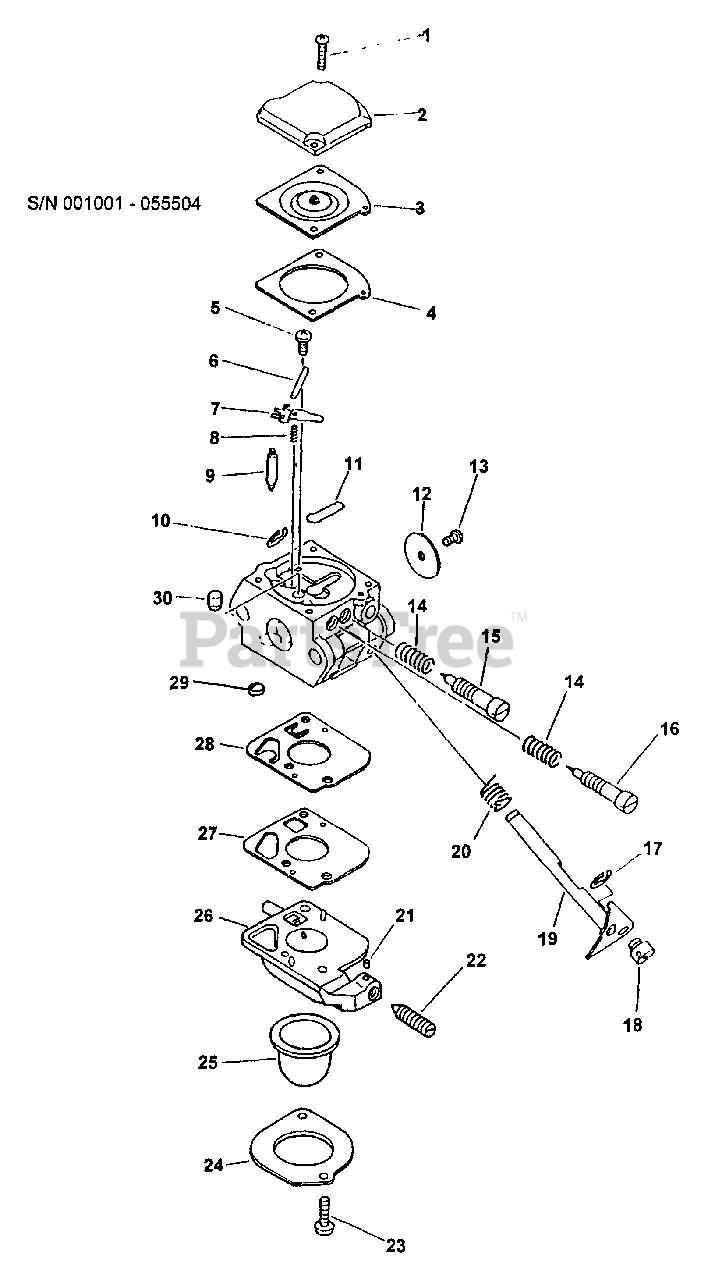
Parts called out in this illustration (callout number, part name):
2	COVER, METERING
3	DIAPHRAGM, METERING
4	GASKET, METERING
5	SCREW, METERING LEVER PIN
6	PIN
7	LEVER, METERING
8	SPRING, METERING LEVER
9	VALVE, NEEDLE
10	RING, RETAINING
11	PLUG, WELCH
12	VALVE, THROTTLE
15	NEEDLE - LOW SPEED
16	NEEDLE - HIGH SPEED
17	RING, RETAINING
19	SHAFT, THROTTLE
20	SPRING, RETURN
21	PIECE, FRICTION
22	SCREW, IDLE ADJUST
23	SCREW, RETAINER
24	RETAINER, PURGE BULB
25	BULB, PURGE
26	BASE, PURGE
27	GASKET, PURGE
28	DIAPHRAGM, PURGE
29	STRAINER
30	NOZZLE, CHECK VALVE
